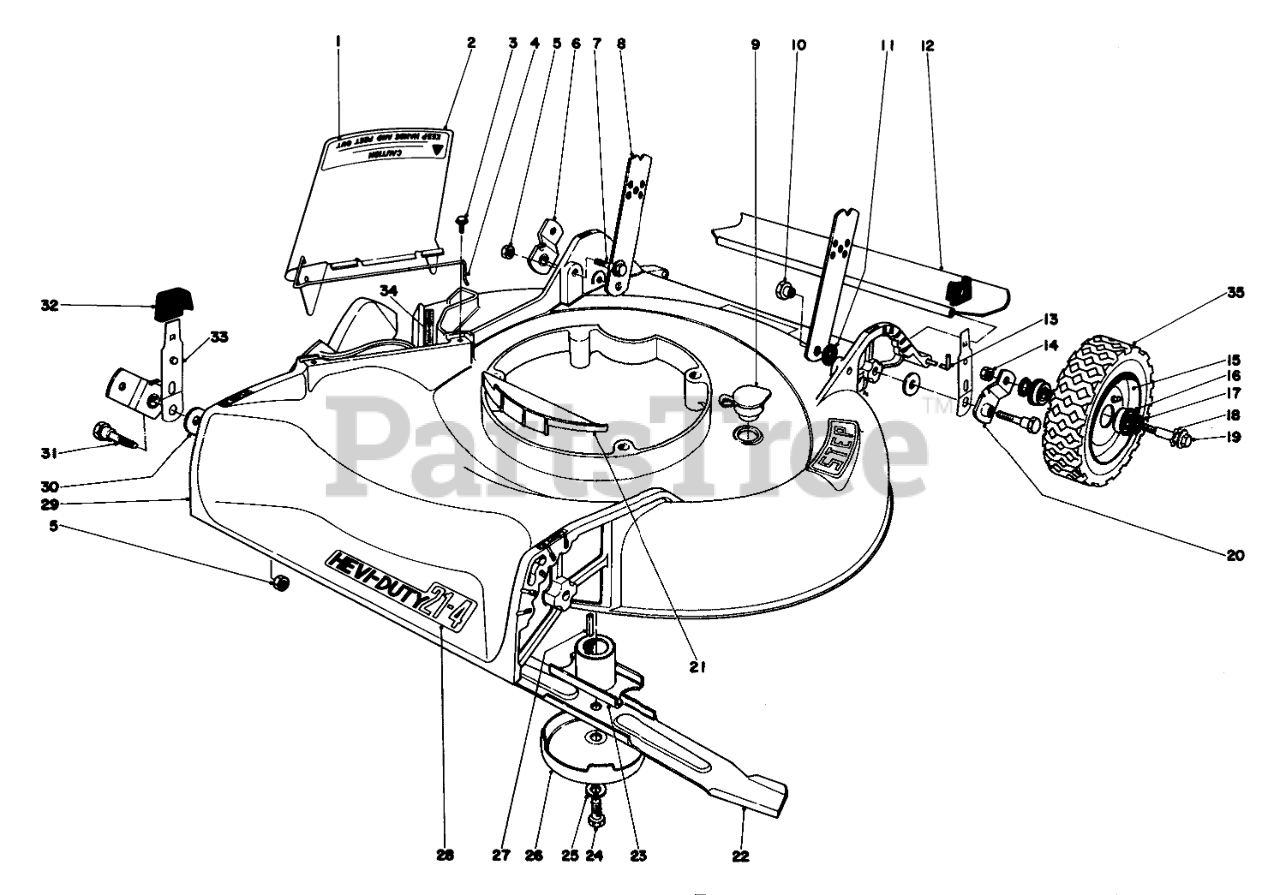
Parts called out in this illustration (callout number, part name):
1	Caution Decal
2	Deflector Cover Assembly (Incl. Ref. #1 & 4)
3	SCREW
4	SPRING HINGE
5	Nut
6	Pivot Arm
7	SCREW-SHOULDER
8	HANDLE LATCH
9	WASHOUT PLUG
10	HANDLE PIVOT NUT
11	HANDLE LATCH SPACER
12	REAR SAFETY SHIELD 21
13	SHIELD ROD
14	Nut
15	Wheel & Tire Assembly (Incl. Ref. #35)
16	BEARING-BALL
17	FELT WASHER
18	SPRING WASHER
20	Pivot Arm
21	HOUSING CAP
22	Blade
23	Blade Retailer
24	SPECIAL SCREW
25	WASHER-LOCK
26	AntiScalp Cup
27	KEY-SQUARE
28	Decal-21-4 Hevi-Duty
29	Housing
30	WASHER-PIVOT
31	PIVOT SCREW
32	KNOB-ARM
33	SPRING ARM ASM
34	Decal
